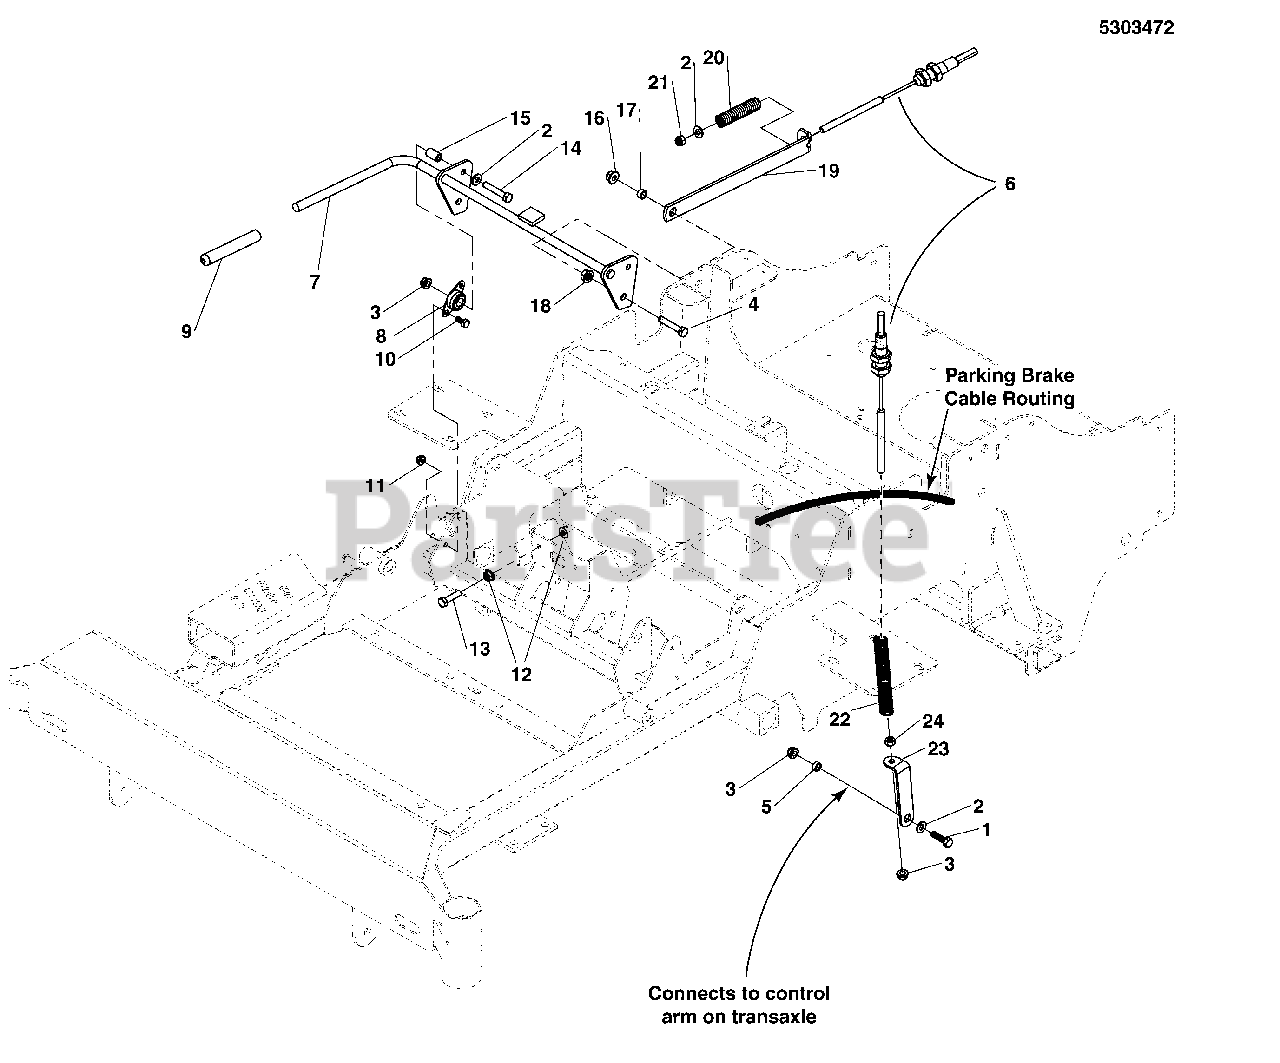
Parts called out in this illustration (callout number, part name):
1	BOLT, 5/16-18 X 1-1/8 GD5
2	WASHER, 5/16 SAE
3	NUT, 5/16-18 HEX NYLOCK FLANGE
4	SCREW,3/8-16X1.500,HEX WSHR HD,TT,ZC/CL (80005605)
5	SPACER, .33 X .50 X .25, CZ
6	CABLE, PARKING BRAKE, 25.06" (636.6 MM)
7	WELD, BRAKE SHAFT, IS600 - BLK
8	BEARING, 1/2 FLANGED, PLASTIC BALL
9	GRIP, FOAM, .475 X 4.35 X .095
10	BOLT,1/4-20X5/8
11	NUT, 1/4-20 HEX NYLOCK FLANGE
12	NUT, 5/16-18 HEX SERRATED FLANGE (SMALL)
13	BOLT, 5/16-18 X 1-1/4 GD5 YZ
14	BOLT, 5/16-18 X 1-3/4 GD5 YZ
15	SPACER, .32 X .50 X .83, CZ
16	NUT, 3/8-16 HEX SERRATED FLANGE
17	SPACER, .38 X .50 X .27, CZ
18	NUT, 3/8-16 HEX NYLOCK FLANGE
19	LINK, BRAKE LOCK, IS700 - BLK
20	SPRING-COMP, .496ID X 3.00LG X .112WR
21	NUT, 5/16-24 HEX NYLON LOCK
22	SPRING-COMP, .600ID X 5.50LG X .080WR
23	LINK, LOWER BRAKE, IS700 - BLK
24	NUT, 5/16-18 HEX
